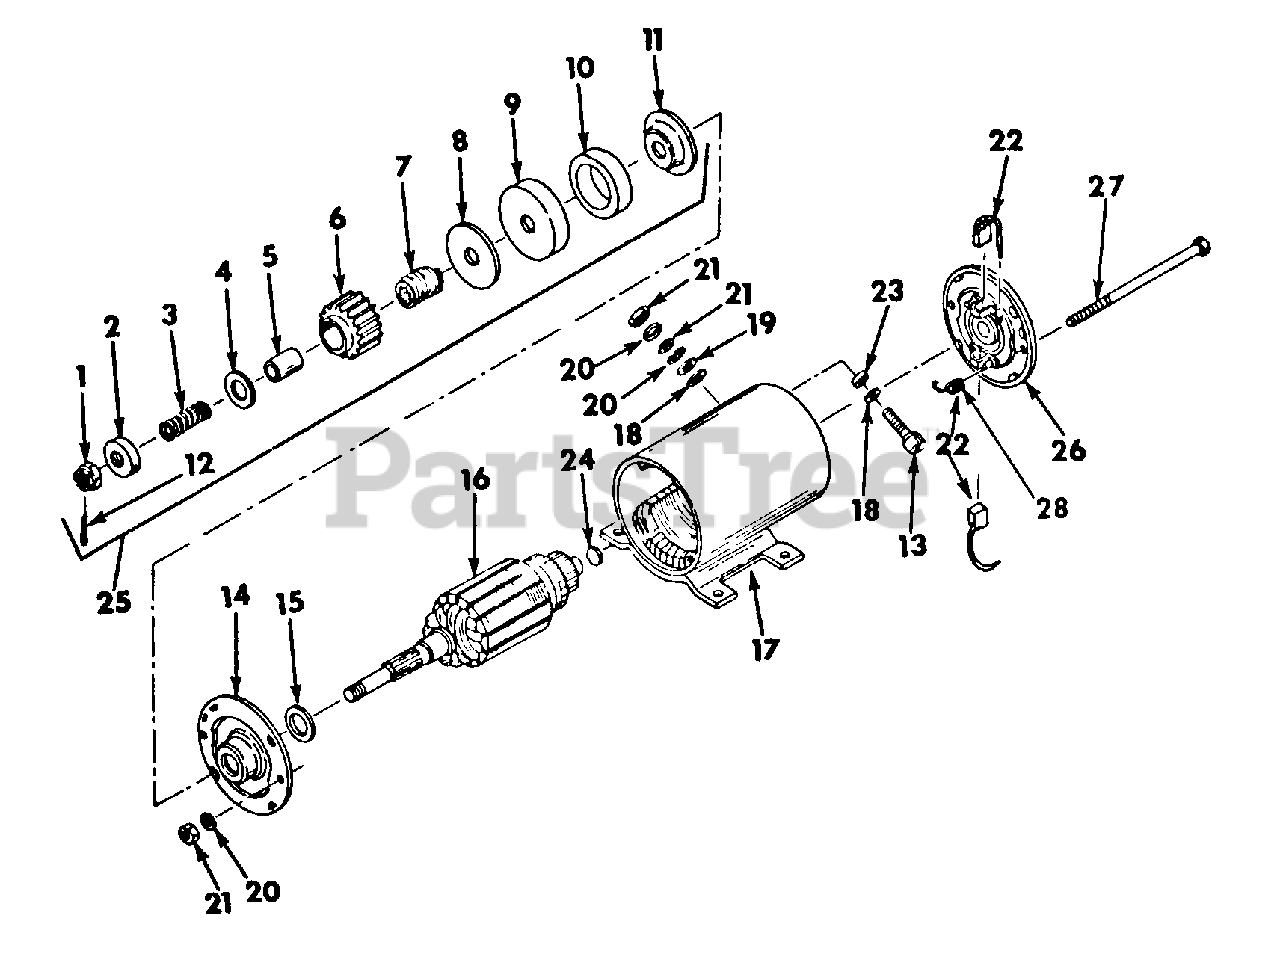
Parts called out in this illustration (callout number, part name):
2	STOP, PINION
3	SPRING, ANTI-DRIFT
4	WASHER, PINION
5	SLEEVE, ANTI-DRIFT
6	GEAR, PINION
7	SHAFT, SCREW
8	WASHER, THRUST
9	CUP, CUSHION
10	CUSHION, RUBBER
11	WASHER, THRUST
13	BOLT, TERMINAL
14	CAP ASSY, DRIVE END W/BRG
15	WASHER, SPACING .024
17	HOUSING ASSY
18	WASHER, INSULATING
19	WASHER, 17/64 X 1/2 X 16 GA C-Z
20	WASHER, LOCK
22	BRUSH & SPRING KIT
23	BUSHING, INSULATING
24	WASHER, SPACING
26	END CAP ASSY, COMMUTATOR
28	SPRING, BRUSH
